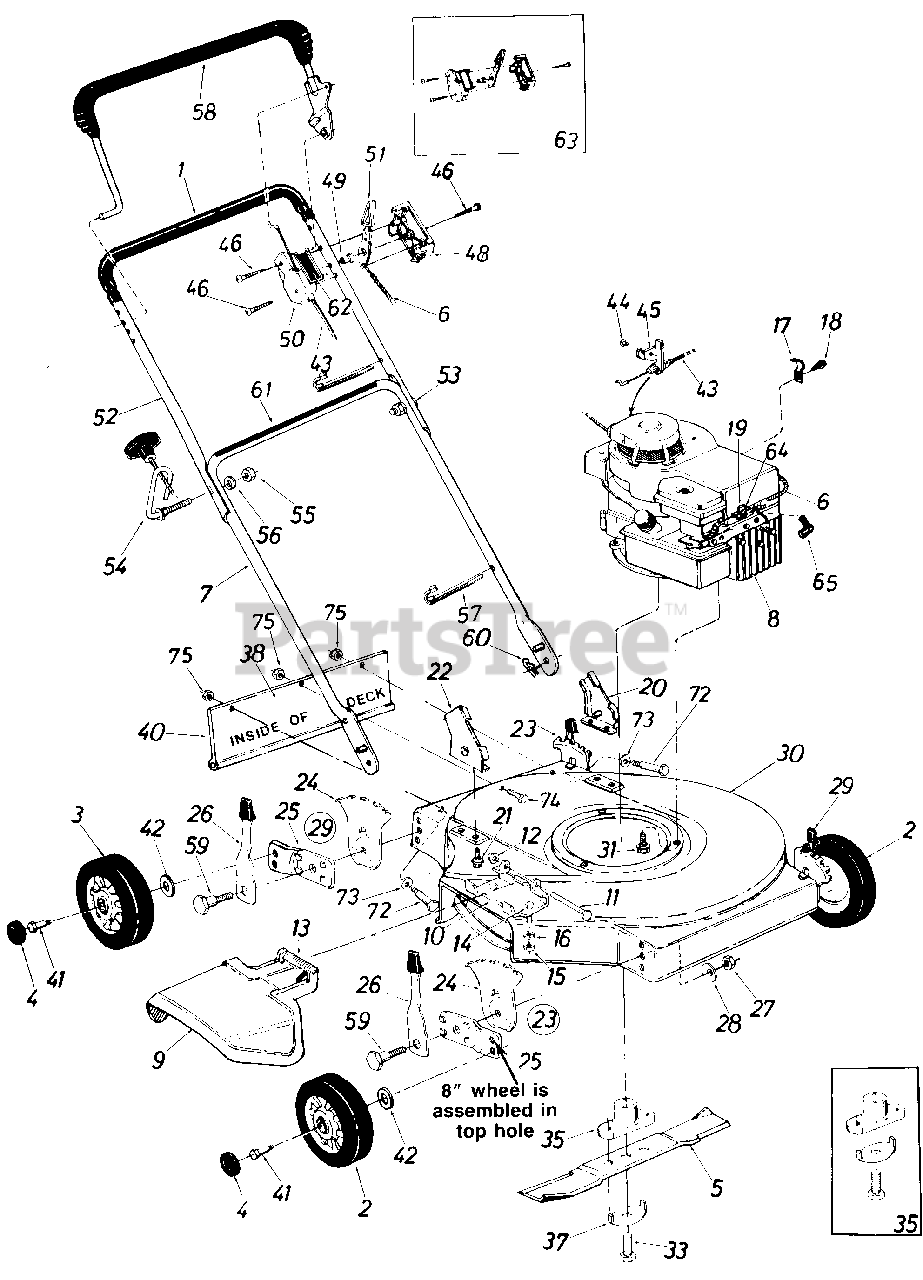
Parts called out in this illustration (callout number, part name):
2	Front Wheel Ass'y. Comp.
3	Rear Wheel Ass'y. Comp.
4	Hub Cap
5	20" Blade
6	Throttle Wire 53"
7	Lower Handle
8	Engine
9	Chute Deflector Ass'y. Comp.
10	Adapter Plate
11	Pivot Pin
12	Push Cap 1/4" Rod
13	Torsion Spring
14	Hex Bolt 1/4-20 x .50" Lg.
15	Hex Nut 1/4-20 Thd.
16	L-Wash. 1/4" I.D.
17	Cable Clip
18	Hex AB-Tap Scr. #10 x .38" Lg.
19	Casing Clamp
20	Handle Brkt. Ass'y. L.H.
21	Hex Wash. Hd. B-Tap Scr. 5/16-18 x .50" Lg.
22	Handle Brkt. Ass'y. R.H.
23	Height Adjuster Ass'y. Comp. R.H.
24	Index Plate
25	Pivot Bar
26	Spring Lever Ass'y. w/ Knob
27	Hex Nut 3/8-16 Thd.
28	Bell-Wash. .39" I.D. x 1.13" 0. D.
29	Height Adjuster Ass'y. Comp. L.H.
30	20" Deck Ass'y. Comp.
31	Hex Wash. Hd. TT-Tap Scr 3/8-16 x 1.0" Lg.
33	Hex Bolt 3/8-24 x 1.5" Lg. (Grade 5)
35	Blade Adapter Kit
37	Blade Bell-Wash. .45" I.D. x 2.38"
38	Retaining Strip
40	Rear Flap Ass'y.
41	Axle Bolt
42	Bell-Wash. .400" I.D. x .88" O.D.
43	Control Cable 35"
44	Cable Brkt.
45	Pop Rivet .156" Dia. x .379
46	Truss. Mach. Self-Tap Scr. #12 x 1.5" Lg.
48	Control Panel Half
49	Control Disc Pin
50	Clutch Panel Half
51	Throttle Control Lever
52	Upper Handle
53	Curved Carriage Bolt 5/16-18 x 1.38" Lg.
54	Rope Guide Bolt
55	Hex Nut 5/16-18 Thd.
56	L-Wash. 5/16" I.D.
57	Cable Tie
58	Control Handle Ass'y. L.H.
59	Shld. Bolt .500" Dia. x .375
60	Hairpin Cotter
61	Instruction Label Handle
62	Control Label
63	Kit Control Housing Comp.
64	Hex Wash. Hd. AB-Tap Scr. #8 x .38" Lg.
65	Spark Plug Insulator
72	Shld. Bolt. 3/8" Dia. x 1.16" Lg.
73	Flat Wash. .28" I.D. x .75 0. D.
74	Hex Bolt 1/4-20 x .50" Lg.
75	Hex Ins. L-Nut 1/4-20 Thd.
